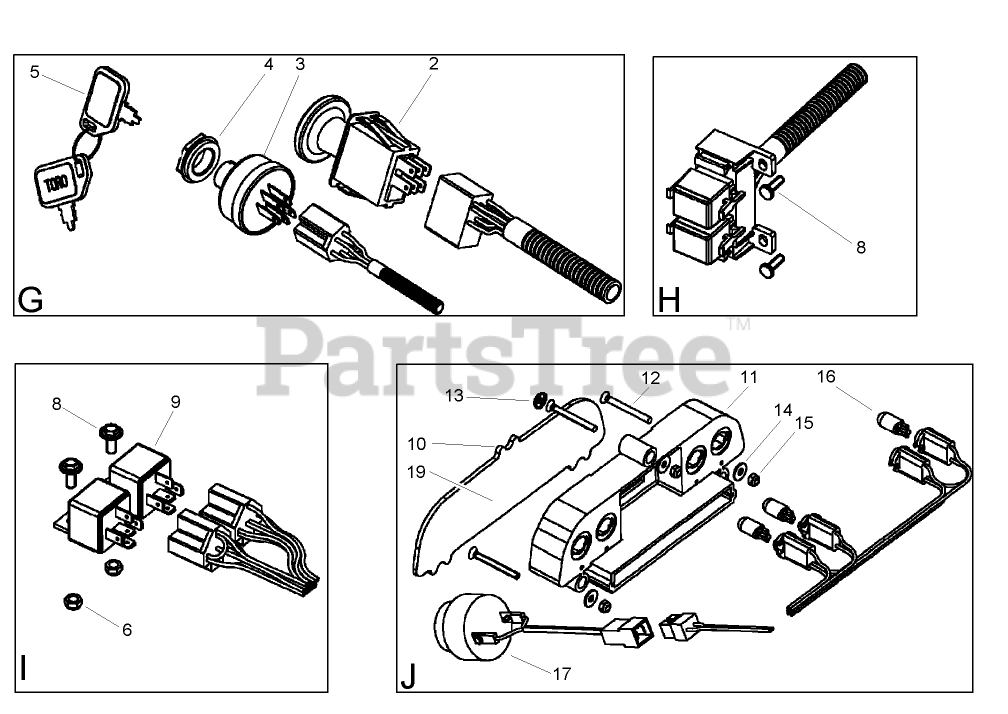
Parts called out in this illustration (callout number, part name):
2	SWITCH-PTO,ON-ON-NONE
3	SWITCH-IGNITION
4	NUT-HEX
5	KEY-IGNITION
6	NUT-LOCK
8	SCREW-HEX
10	LENS-DASH LIGHTS
11	HOUSING-LIGHT, INDICATOR
13	CAP-SCREW
14	WASHER
15	NUT-HEX
17	BUZZER
19	DECAL-DASH
